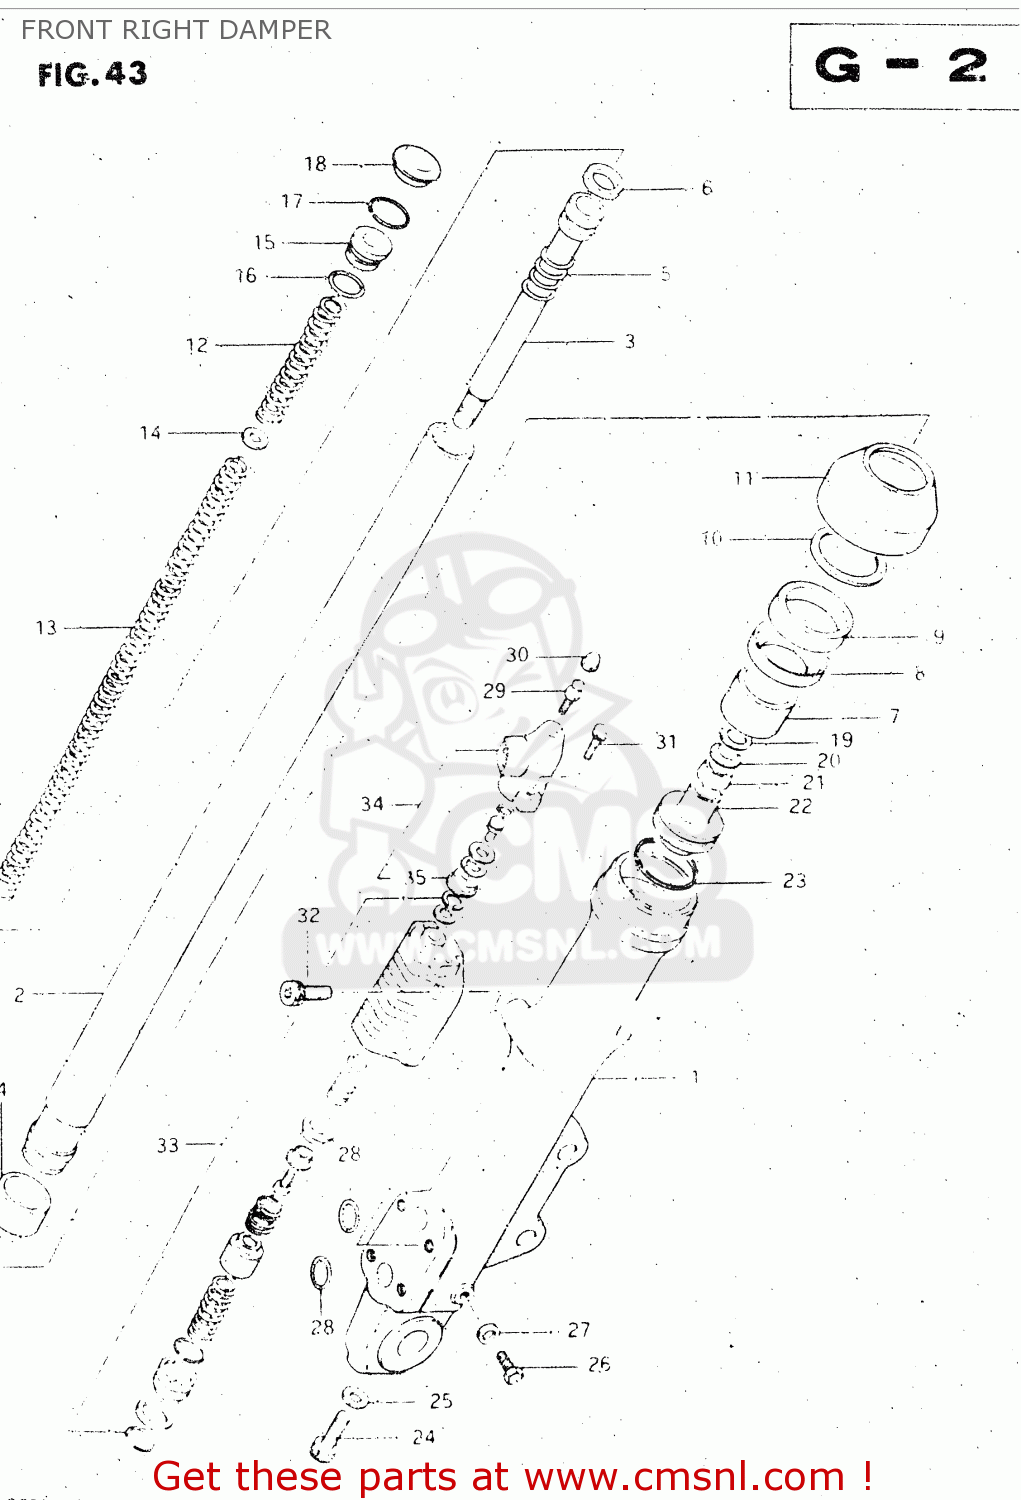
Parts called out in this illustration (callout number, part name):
1	OUTER TUBE RH
2	INNER TUBE
3	CYLINDER
4	PISTON
5	SPRING,FORK REBOUND
6	RING
7	BUSH,GUIDE
8	SPACER,SEAL
9	OIL SEAL,FRONT FORK
10	CIRCLIP,FORK OIL SEAL
11	BOOT
12	SPRING (A)
13	SPRING (B)
14	WASHER,SPRING
15	SPRING SEAT B
16	O-RING
17	RING,STOPPER
18	CAP
19	VALVE
20	SPRING,VALVE
21	VALVE,OIL LOCK PIEACE
22	PIECE,FRONT FORK OIL LOCK
23	PISTON RING,FRONT FORK
24	BOLT(8X27)
25	GASKET (NAS)
26	BOLT
27	GASKET
28	O RING,FR FORK
29	BREATHER
30	CAP
31	BOLT
32	BOLT
33	MODULATOR VALVE SET
34	MODULATOR PLANGER SET
35	SEPARATOR,FRONT FORK MODULATOR
